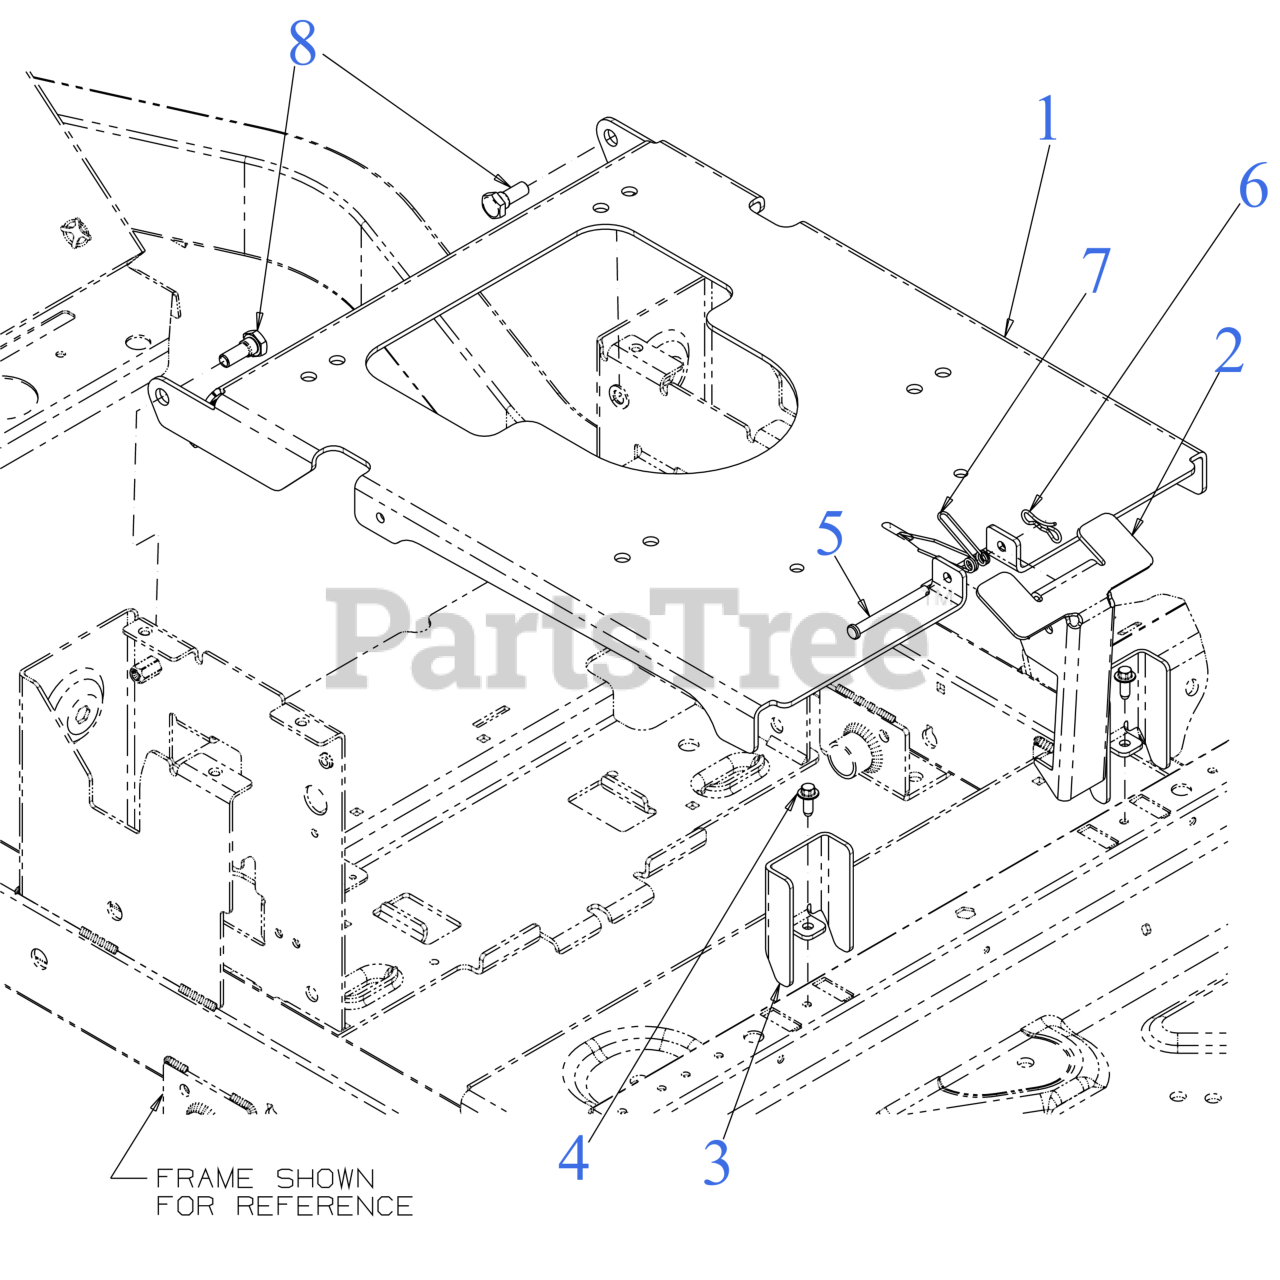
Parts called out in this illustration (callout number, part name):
1	SEAT BASEPLATE
2	SEAT LATCH BRACKET
3	SEAT SUPPORT
4	SCREW M6-1 x .625
5	CLEVIS PIN .248 x 2.345
6	BOW TIE COTTER PIN 1/4-5/16
8	SHOULDER SCREW .437
